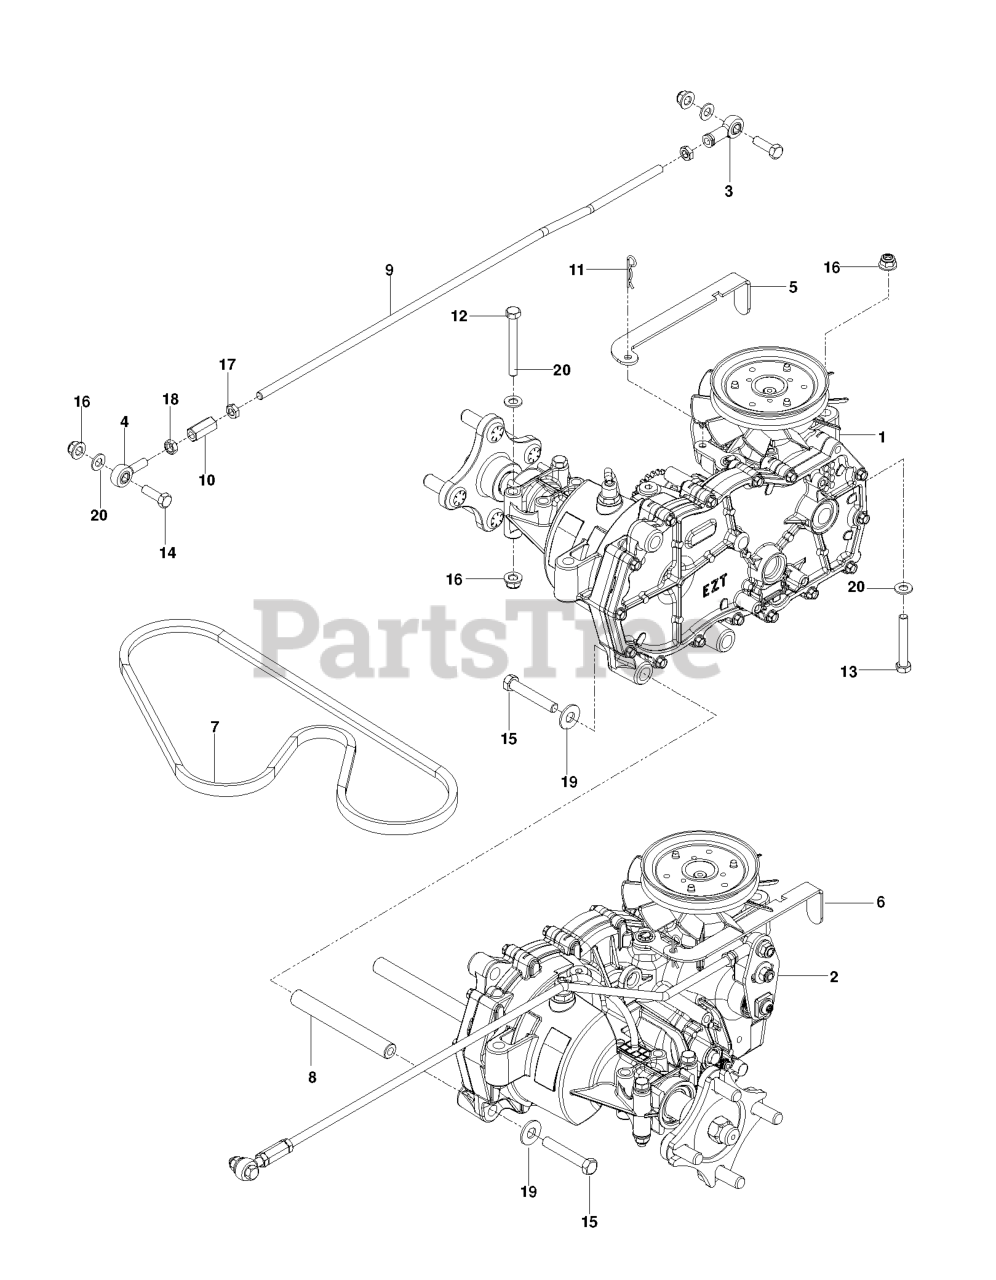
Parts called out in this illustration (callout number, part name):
1	HG_HYDRO RH
2	HG_HYDRO LH
3	RH ROD END
4	RB ROD.END.LH
5	RELEASE LEVER RH
6	RELEASE LEVER LH
7	BELT, EL 51.O4
8	SPACER, HYDRO
9	CONTROL ROD
10	ROD END COUPLER
11	HAIRPIN #2
12	HCS 5/16C X 2-3/4
14	HCS 5/16C X 1
15	HCS 3/8C X 2 1/4
16	5/16-18 NYLOC FLANGE NUT
17	NUT 5/16-24 UNF HEX JAM
18	NUT 5/16F LEFTHAND
19	RP WASHER 3/8 FLAT
20	FLAT WASHER 5/16 SAE
